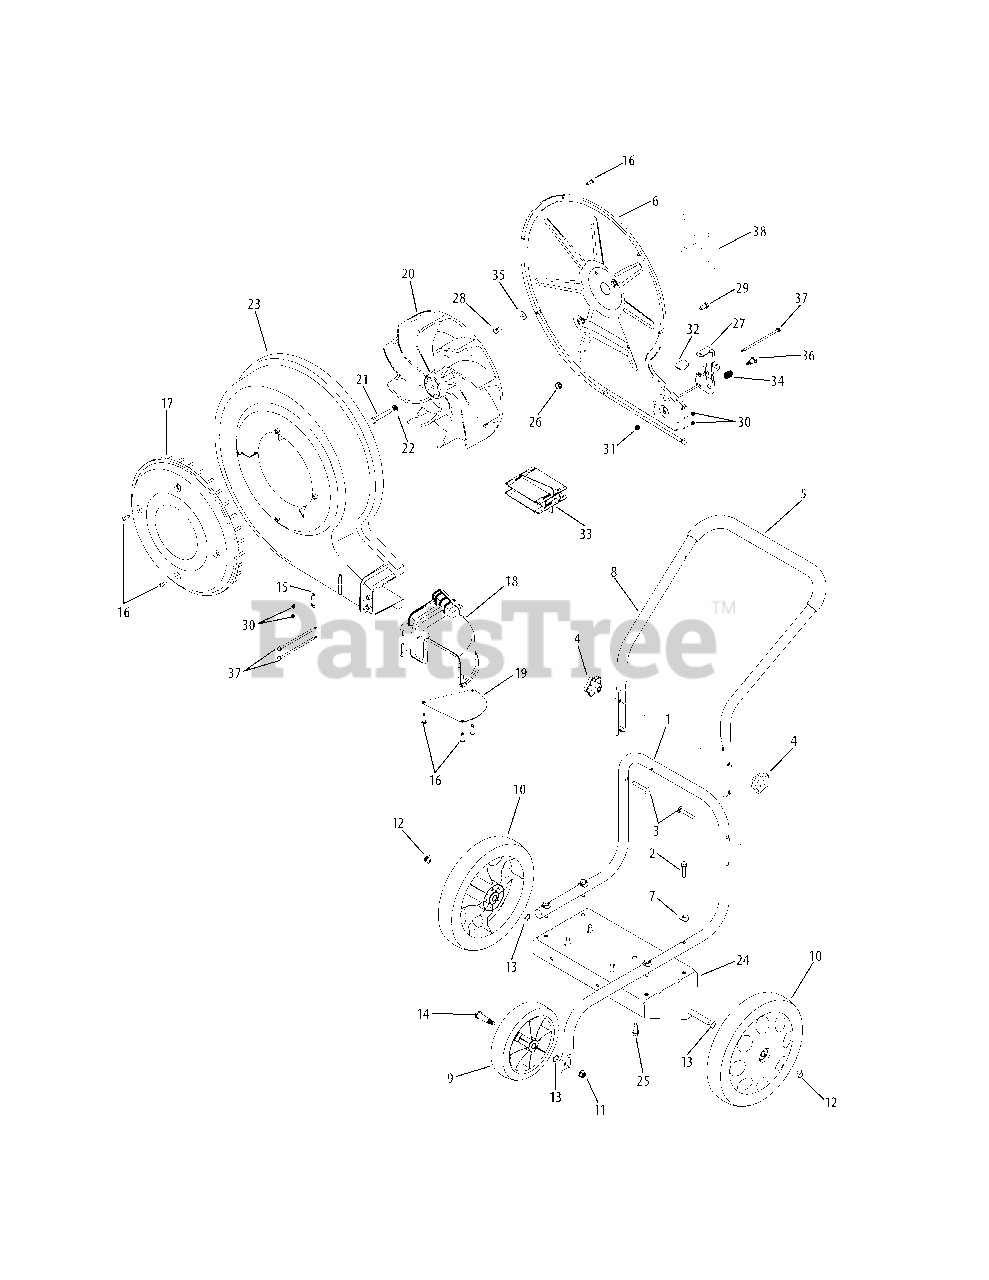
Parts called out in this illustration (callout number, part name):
1	Lower Handle Assembly
2	Hex Screw, 5/16-18 x 1.50
3	Carriage Screw, 5/16-18 x 2.00
4	Star Knob, 5/16-18
5	Foam Grip, .970 x 25
6	Back Plate
7	Saddle Washer, .320 x .93 x .060
9	Wheel, 8 x 2
10	Wheel, 12"
11	Flange Lock Nut, 3/8-16
12	Push Cap, 1/2"
13	Wave Washer, .510 x .750 x .017
14	Shoulder Screw, .498 x 1.445
16	Hex Screw, 12-16 x .75
17	Blower Cover
18	Chute Assembly
20	Impeler Assembly
21	Hex Screw, 3/8-24 x 2.25
22	Lock Washer, 3/8
23	Blower Housing
25	Sems Screw, 3/8-16 x 1.000
26	Flange Lock Nut, 5/16-18
28	Hex Bolt, 5/16-24 x .625 (205 CC)
28	Hex Bolt, 5/16-24 x 1.00 (208 CC)
29	Hex Bolt, 5/16-18 x .75
30	Hex Lock Nut, #8-32
31	Flange Lock Nut, 1/4-20
32	Height Adjustment Knob
33	Louver Plate
34	Comp. Spring, .515 x .641 x .95
35	Bell Washer, .340 x .872 x .060
36	Shoulder Screw, .437 x .50 x 1/4-20
37	Shoulder Screw, .18 x 4.8 x 8-32
38	Engine Plate (208 CC)
